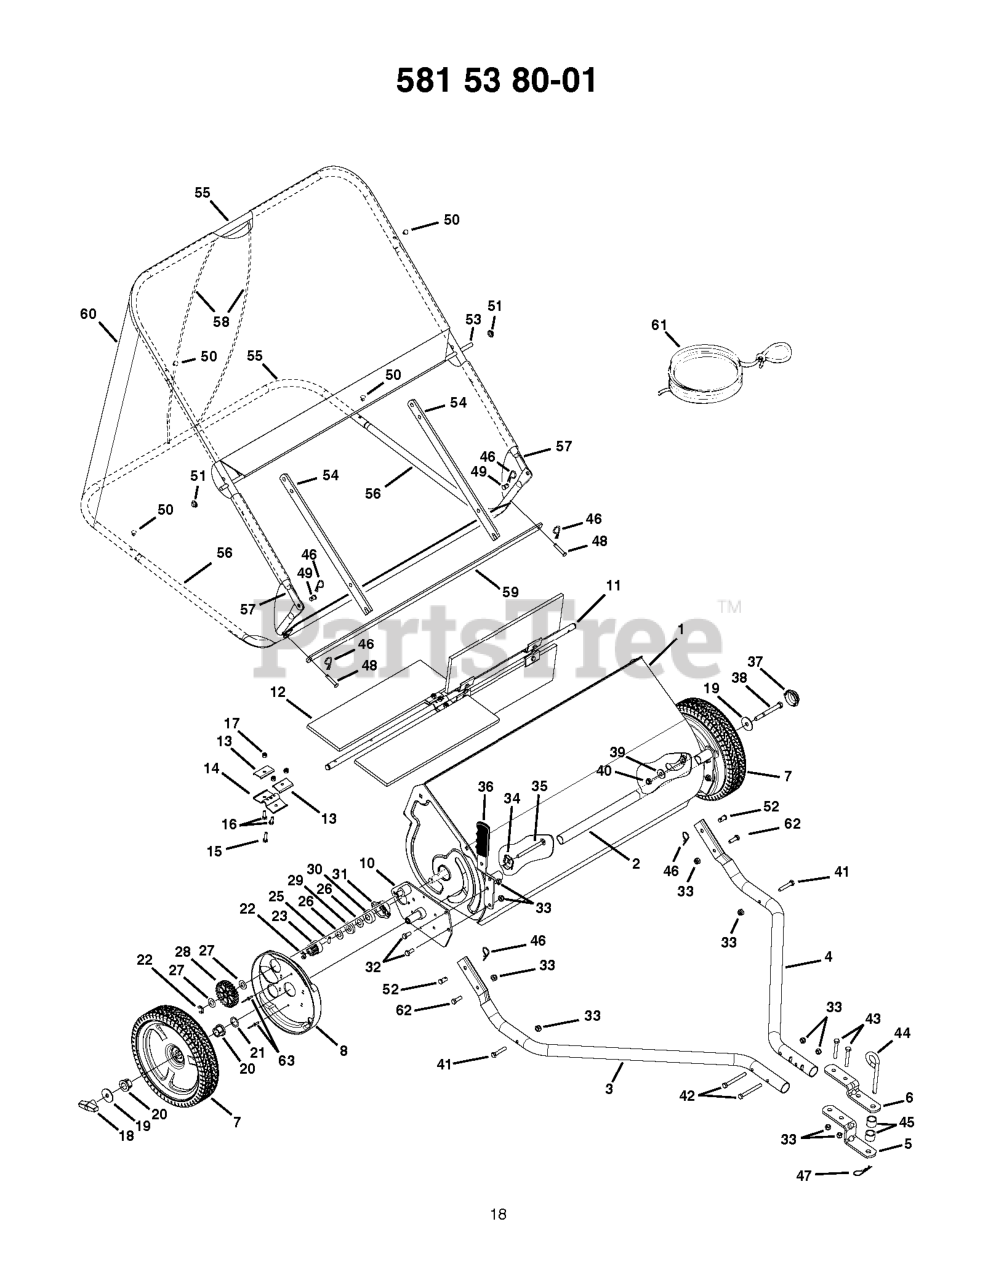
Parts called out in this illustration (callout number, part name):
5	HITCH BRACKET
6	Bracket, Hitch
8	DUST COVER
9	BRACKET
10	BRACKET
13	BRUSH RETAINER SINGLE
14	BRUSHRETAINER DOUBLE
18	Knob, Wing 5/16-18 Thread
21	Washer, Flat 1-1/8" x .78" x .025"
23	PINION
24	PINION
27	Washer, 1/2" x 1" x .02"
30	BALL BEARING
36	Rubber Grip
38	HEX BOLT
41	SCREW
42	Bolt, Hex 5/16-18 x 3" Lg.
44	Pin, Hitch
45	Hitch Adjustment Tube
46	Pin, Hair Cotter 3/32" #3
58	HOPPER SUPPORT ROD
60	HOPPER BAG 32"
